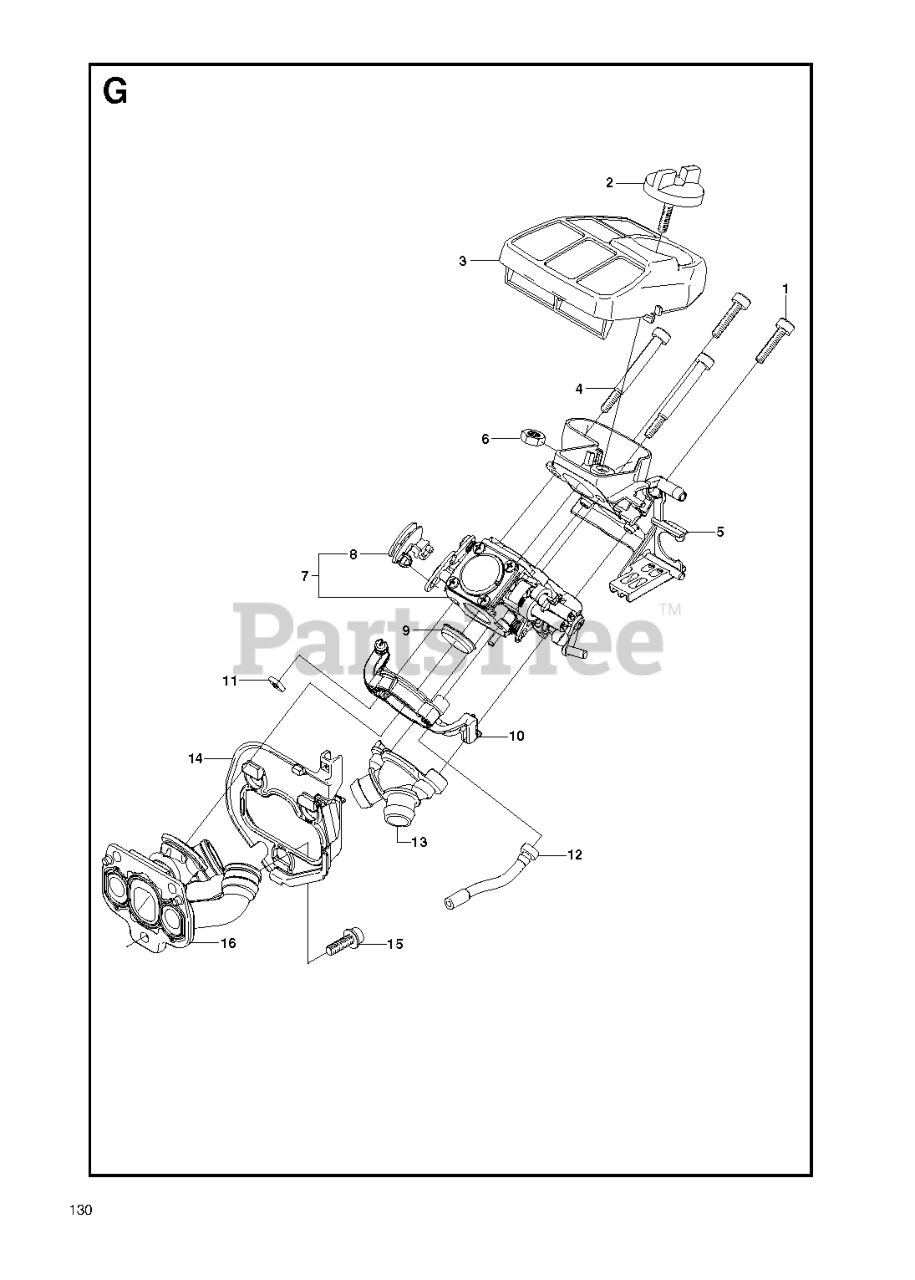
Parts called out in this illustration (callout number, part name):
3	RP AIR FILTER
3	%AIR FILTER
4	SCREW 4X46
5	FILTER HOLDER
7	RP CARBURETOR
10	FLANGE
14	PARTITION
